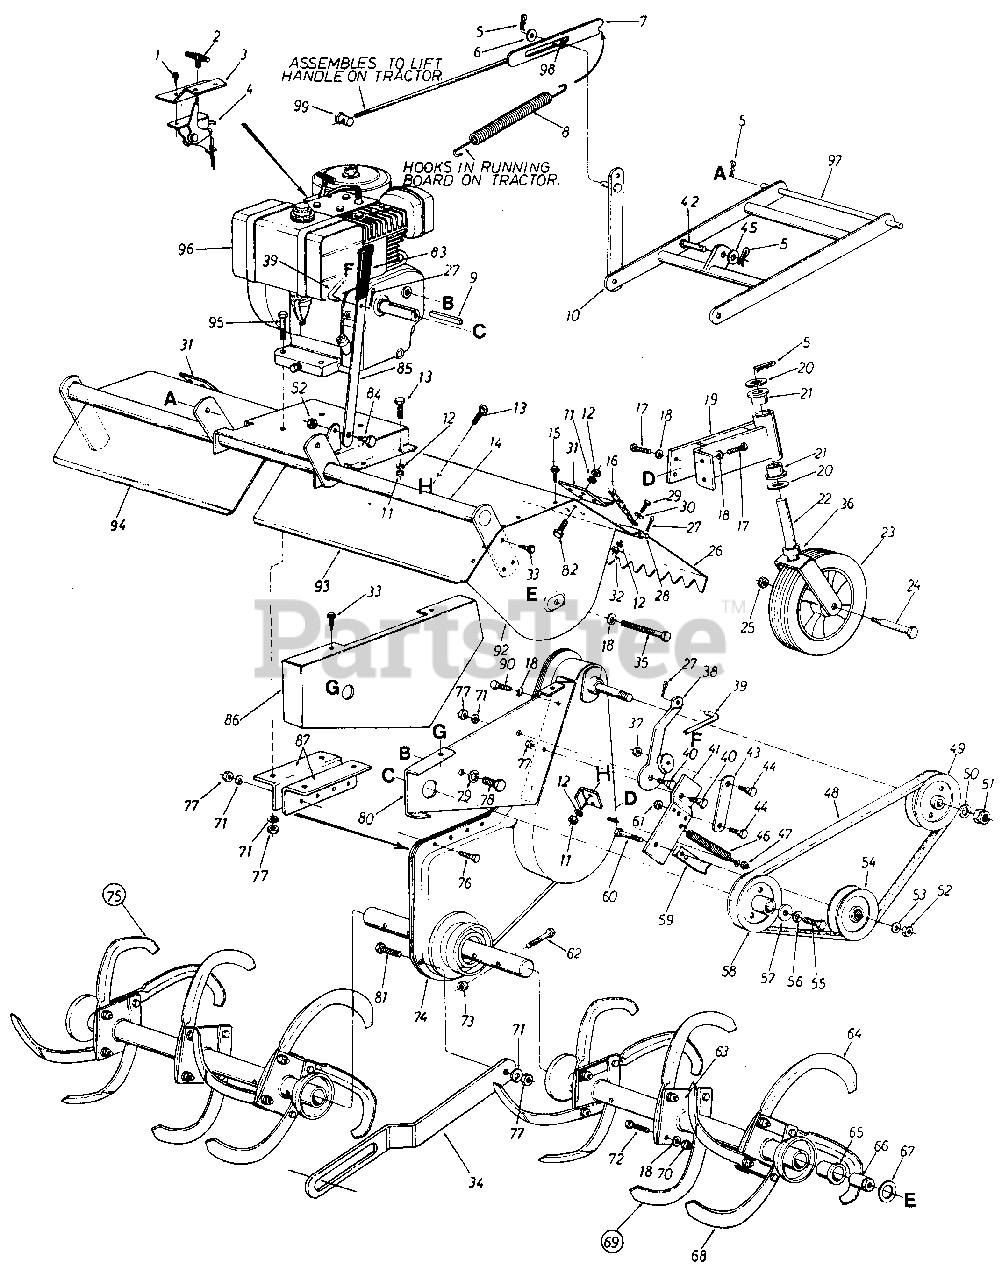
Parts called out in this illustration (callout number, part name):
1	Hex Wash. Hd. Self-Tap Scr. #8 x .50" Lg.
2	Throttle Control Knob
3	Throttle Control Bracket
4	Throttle Control Ass'y.Comp.
5	Internal Cotter Pin
6	Fl-Wash. 1/2" I.D. x .93" O.D.
9	Sq. Key 1/4" x 1/4" x 2.00" Lg.
12	L-Wash. 1/4" I.D.
13	Hex Bolt 1/4-28 x 62" Lg.
16	#2 Dog Chain x 20" Lg.
17	Hex Wash. Hd. Self-Tap Scr. 3/8-24 x .75" Lg.
18	L-Wash. 3/8 I.D.
21	Flange Bearing 3/4" I.D. x 1.00" O.D.
24	Shoulder Bolt .623" I.D. x 3.62" Lg.
25	Hex Cent. L-Nut 7/16-14 Thd.
28	L.H. Flap Rod
29	Hex Bolt 1/4-20 x .62" Lg.
30	Fl-Wash. 1/4" I.D.
33	Hex Wash. Hd. Self-Tap Scr. 1/4" x .62" Lg.
36	Spacer .752" I.D. x 1.25" O.D.
37	Hex Cent. L-Nut 5/16-18 Thd.
40	Shoulder Bolt 7/16" Dia. x 1.75" Lg.
45	Fl-Wash. .50" I.D. x 1.0" O.D. x .06
46	Extension Spring .62" O.D. x 6.12" Lg.
47	Hex Crown Nut 3/8-24 Thd.
48	"V"-Belt 1/2" x 43" Lg. (Kevlar)
49	1/2" "V"-Pulley 4.75" O.D. x .625" Bore
50	L-Wash. 5/8" I.D.
51	Hex Ins. L-Nut 5/8-18 Thd.
52	Hex Cent. L-Nut 3/8-16 Thd.
53	Fl-Wash. 3/8 I.D.
54	Idler Pulley 4.0" O.D.
55	Hex Bolt
56	L-Wash. 7/16" I.D.
57	Fl-Wash. 7/16" I.D. x 1.38" O.D.
58	1/2" 'V"-Pulley .475" O.D. x 1.00" Bore
61	Hex Cent. L-Nut 5/16-18 Thd.
62	Hex Bolt 7/16-14 x 2.00" Lg.
66	Spacer
67	Thrust Wash. 1/2" I.D. x 1.55" O.D.
71	L-Wash. 5/16" I.D.
72	Hex Bolt 3/8-24 x 1.5" Lg.
73	Hex Cent. L-Nut 7/16-14 Thd.
77	Hex Nut 5/16-18 Thd.
78	Hex Bolt 1/2-20 x .88" Lg. (Grade 5)
79	L-Wash. 1/2" I.D.
80	Clutch Support Bracket
81	Shld. Bolt .435 Dia. x .265 5/16-18 Thd.
82	Hex Bolt 1/4-28 x .75" Lg.
83	Plastic Grip
84	Shoulder Bolt .498 Dia. x .212 Lg.
96	8 H.P. Engine
97	Hitch Rod
98	Push Bar Sleeve .503" I.D. x .624" O.D.
99	Ferrule
